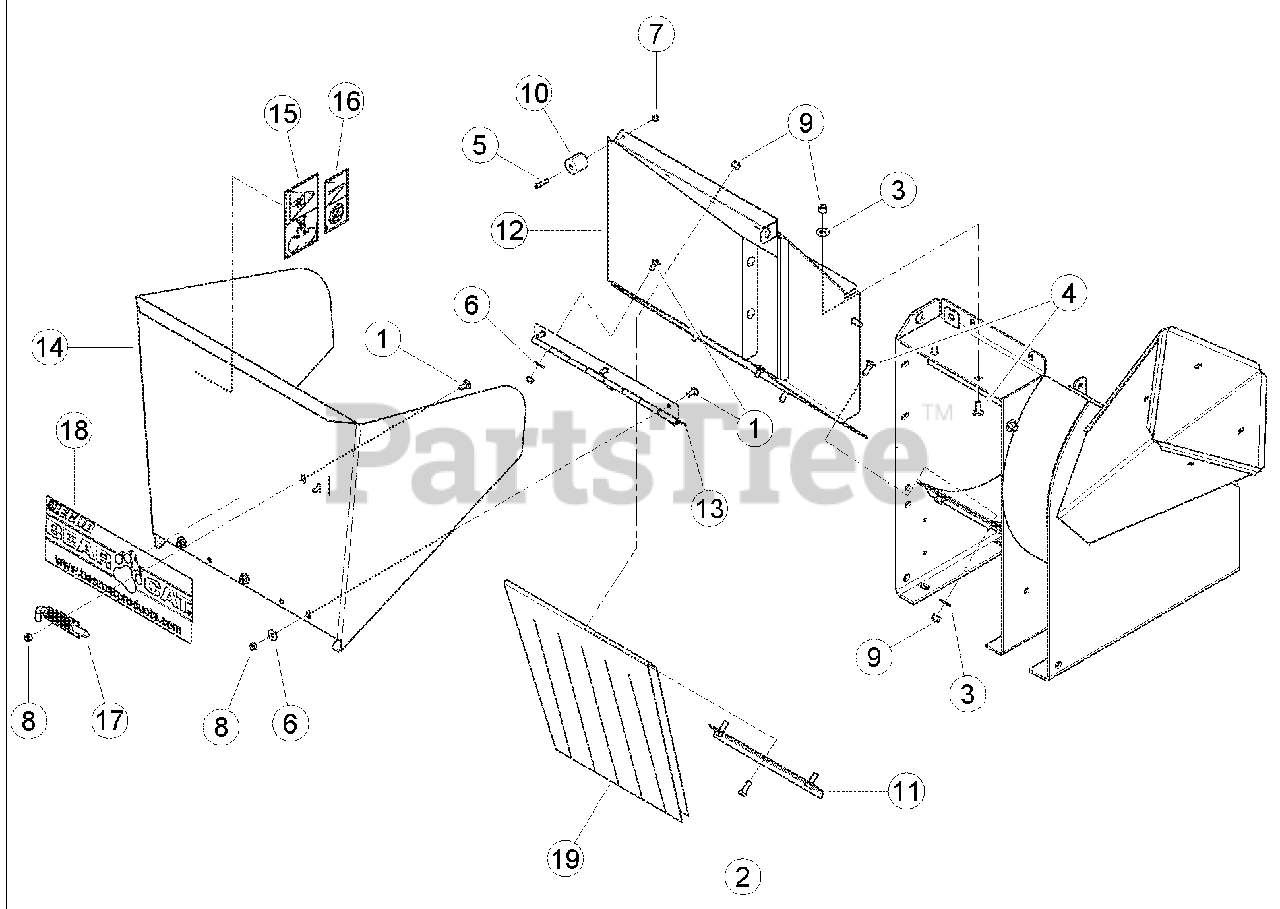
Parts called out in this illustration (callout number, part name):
1	BOLT, 5/16-18 X 3/4 CRG SN GR5
2	BOLT, 3/8 X 1 HEX HD GR5 ZP
3	WASHER, 3/8 FLAT ZP
4	BOLT, 3/8 X 1 CRG GR5 NC ZP
5	BOLT, 1/4 X 1 SOC HD CAP SCRW
6	WASHER, 5/16 FLAT ZP
7	NUT, 1/4 NE NYLOCK ZP
8	NUT, 5/16 NE NYLOCK ZP
9	NUT, 3/8 NE NYLOCK ZP
10	BUMPER, RECESSED RUBBER
11	ANGLE, FLAP ANCHOR
12	WELDMENT, CHUTE
13	HINGE, EXTENSION TRAY
14	ASSEMBLY, EXTENSION TRAY, SERVICE PART
15	DECAL, BLADE DANGER ISO
16	DECAL, SHREDDER SIZE ISO
17	LATCH, RH HINGE
18	DECAL, BEARCAT WEB
19	FLAP, C/S/B CHUTE
